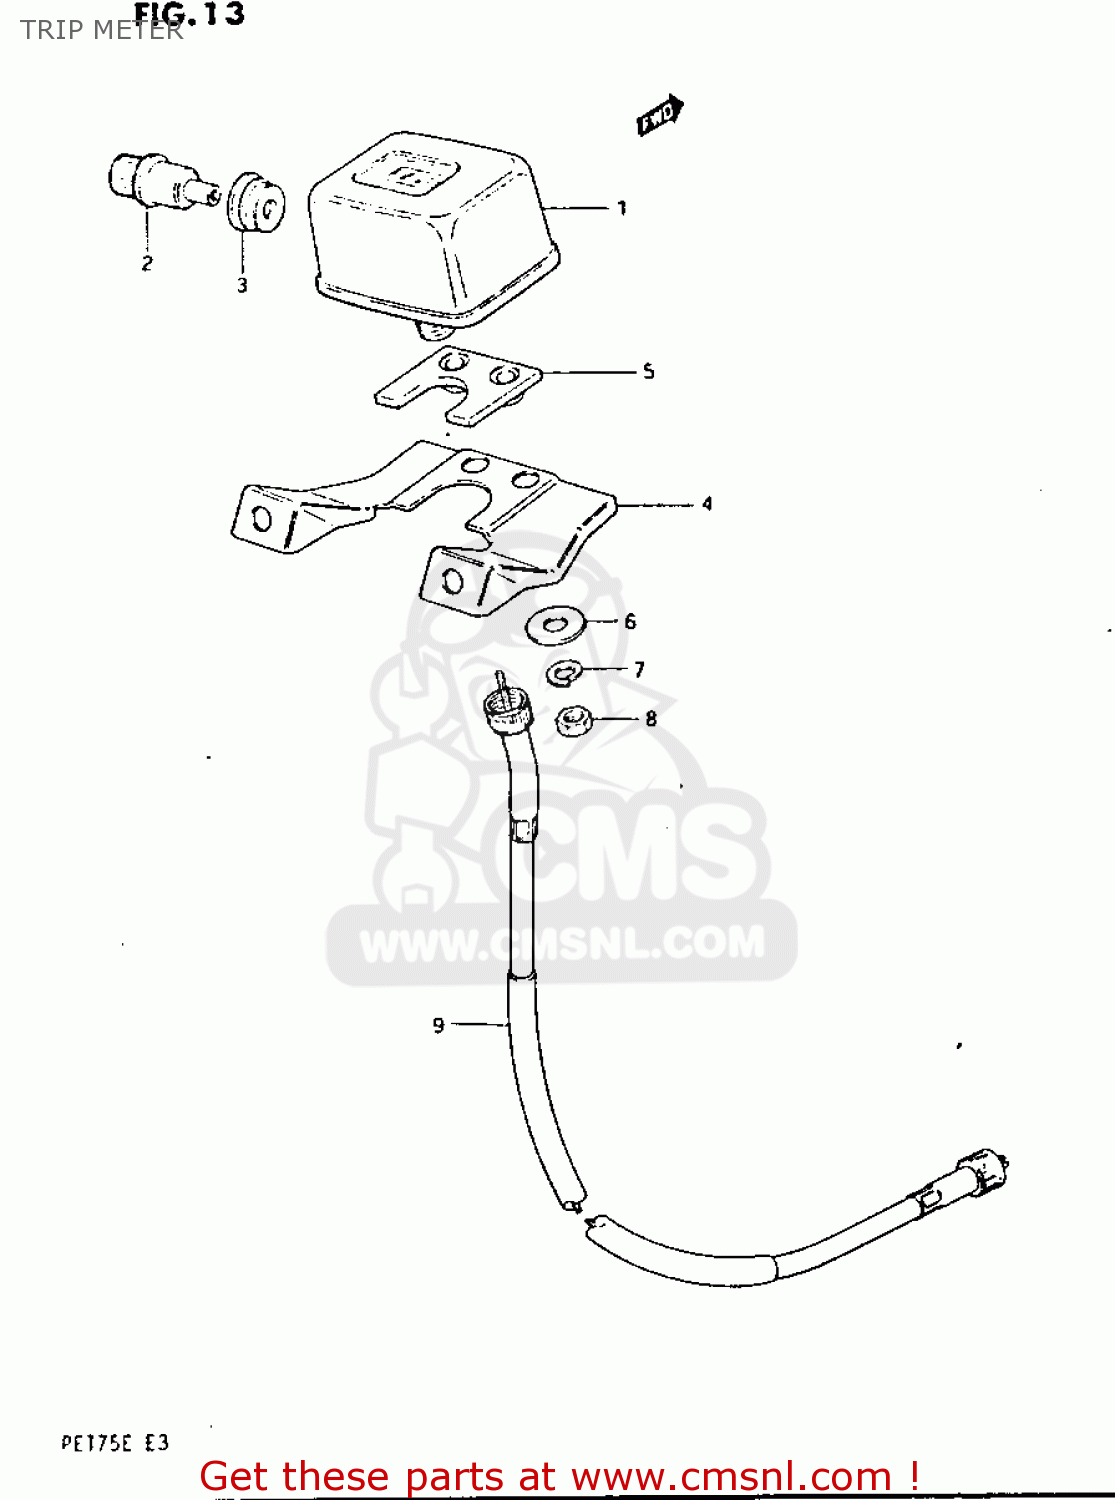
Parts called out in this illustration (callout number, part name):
1	TRIP METER
2	KNOB,TRIP METER
3	COVER,TRIPMETER KNOB
4	BRACKET,TRIPMETER
5	CUSHION,TRIPMETER
6	WASHER,METER
7	WASHER,LOCK 4M
8	NUT
9	CABLE ASSY,SPEEDOMETER
